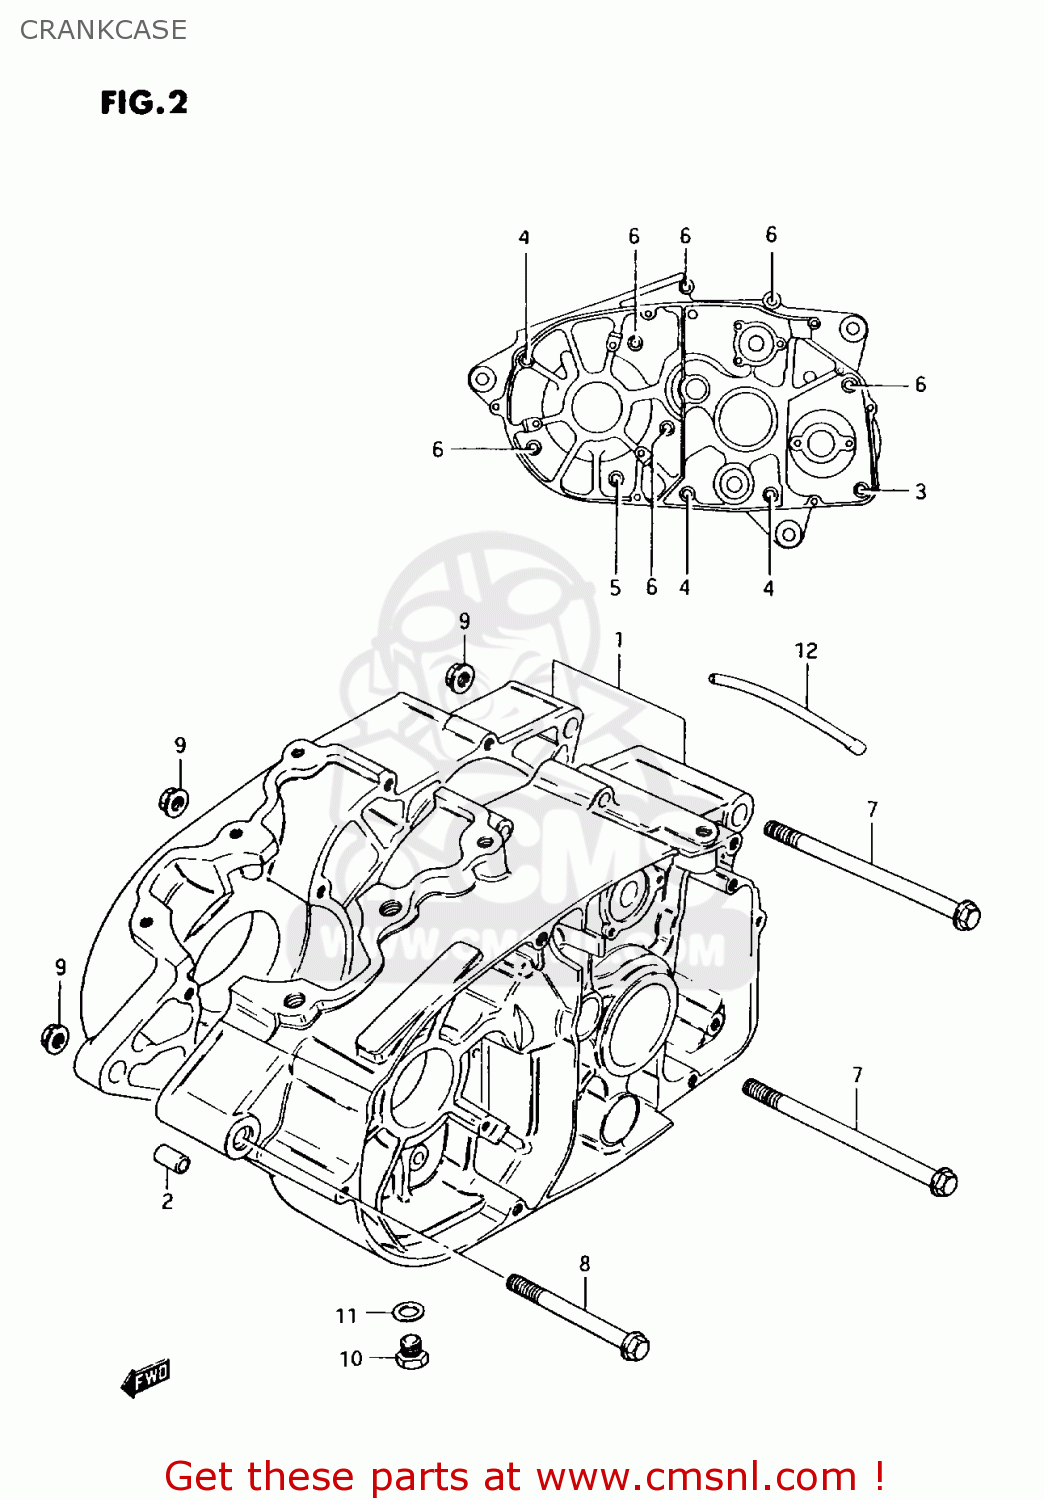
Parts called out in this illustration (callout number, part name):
1	CRANKCASE SET
2	PIN
3	SCREW
4	SCREW
5	SCREW
6	SCREW
7	BOLT(8X115)
8	BOLT(8X75)
9	NUT
10	PLUG
11	GASKET(10X14X3.6) (NAS)
12	HOSE,CARBURETOR AIR VENT
